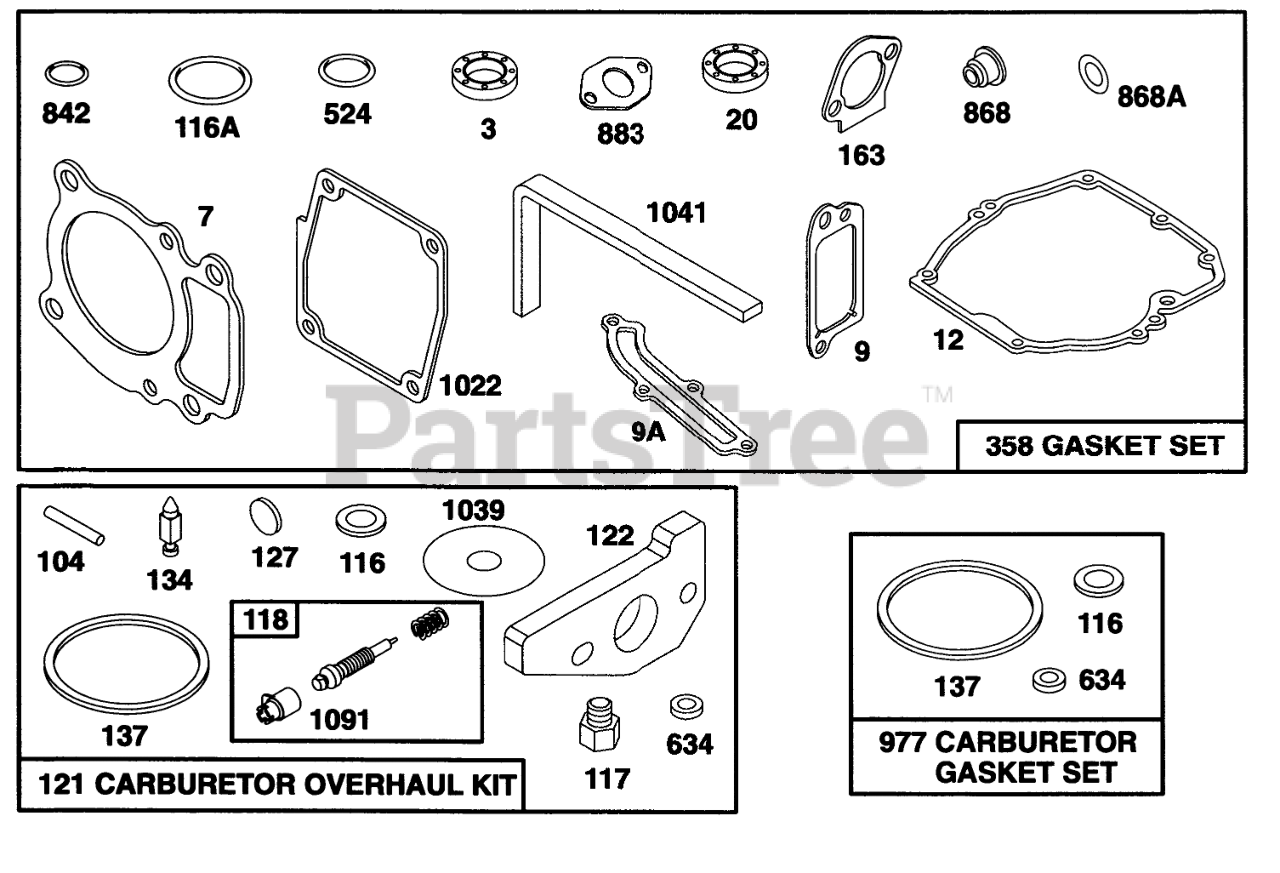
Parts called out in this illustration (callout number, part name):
3	SEAL - OIL
7	CYLINDER HEAD GASKET
9	BREATHER GASKET
9A	GASKET-BREATHER
12	ENGINE BASE GASKET
20	SEAL-OIL
37	GUARD - FLYWHEEL
104	FLOAT HINGE PIN
116	SEALING GASKET
116A	O RING SEAL
117	Jet-Main
118	VALVE/SPRING - NEEDLE
121	KIT-CARBURETOR OVERHAUL
122	ADAPTER ASSEMBLY
127	PLUG - WELCH
134	Valve-Inlet (Includes Seat)
137	FLOAT BOWL GASKET
163	AIR CLEANER GASKET
358	GASKET SET
524	O-RING
634	SEAL WASHER
842	O-RING
868	SealAssy-Valve
868A	Seal-Valve
883	EXHAUST GASKET
977	CARBURATOR GASKET SET
1022	ROCKER COVER GASKET
1039	FLOAT LIMITER
1041	SEAL - FOAM
1091	CAP - LIMITER
